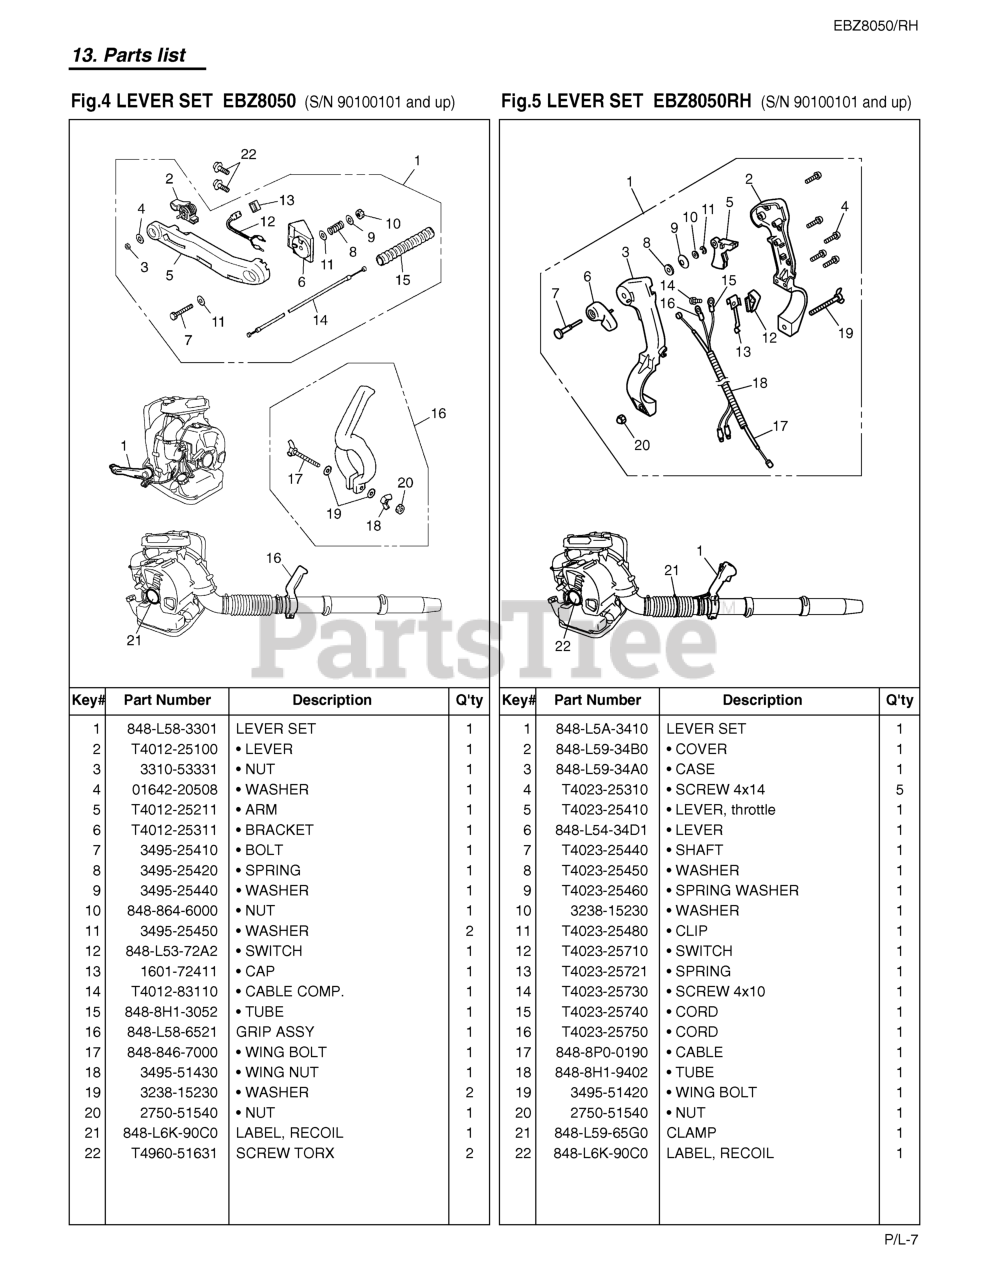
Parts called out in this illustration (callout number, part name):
A1	LEVER (R) SET (rpls848L593411)
A2	COVER
A3	CASE
A4	SCREW 4X14
A5	LEVER, THROTTLE
A6	LEVER
A7	SHAFT
A8	WASHER
A9	SPRING WASHER
A10	WASHER
A11	CLIP
A12	SWITCH
A13	SPRING
A14	SCREW 4X10
A15	CORD
A16	CORD
A17	CABLE
A18	TUBE
A19	BOLT, WING
A20	NUT
A21	CLAMP
A22	LABEL, RECOIL
